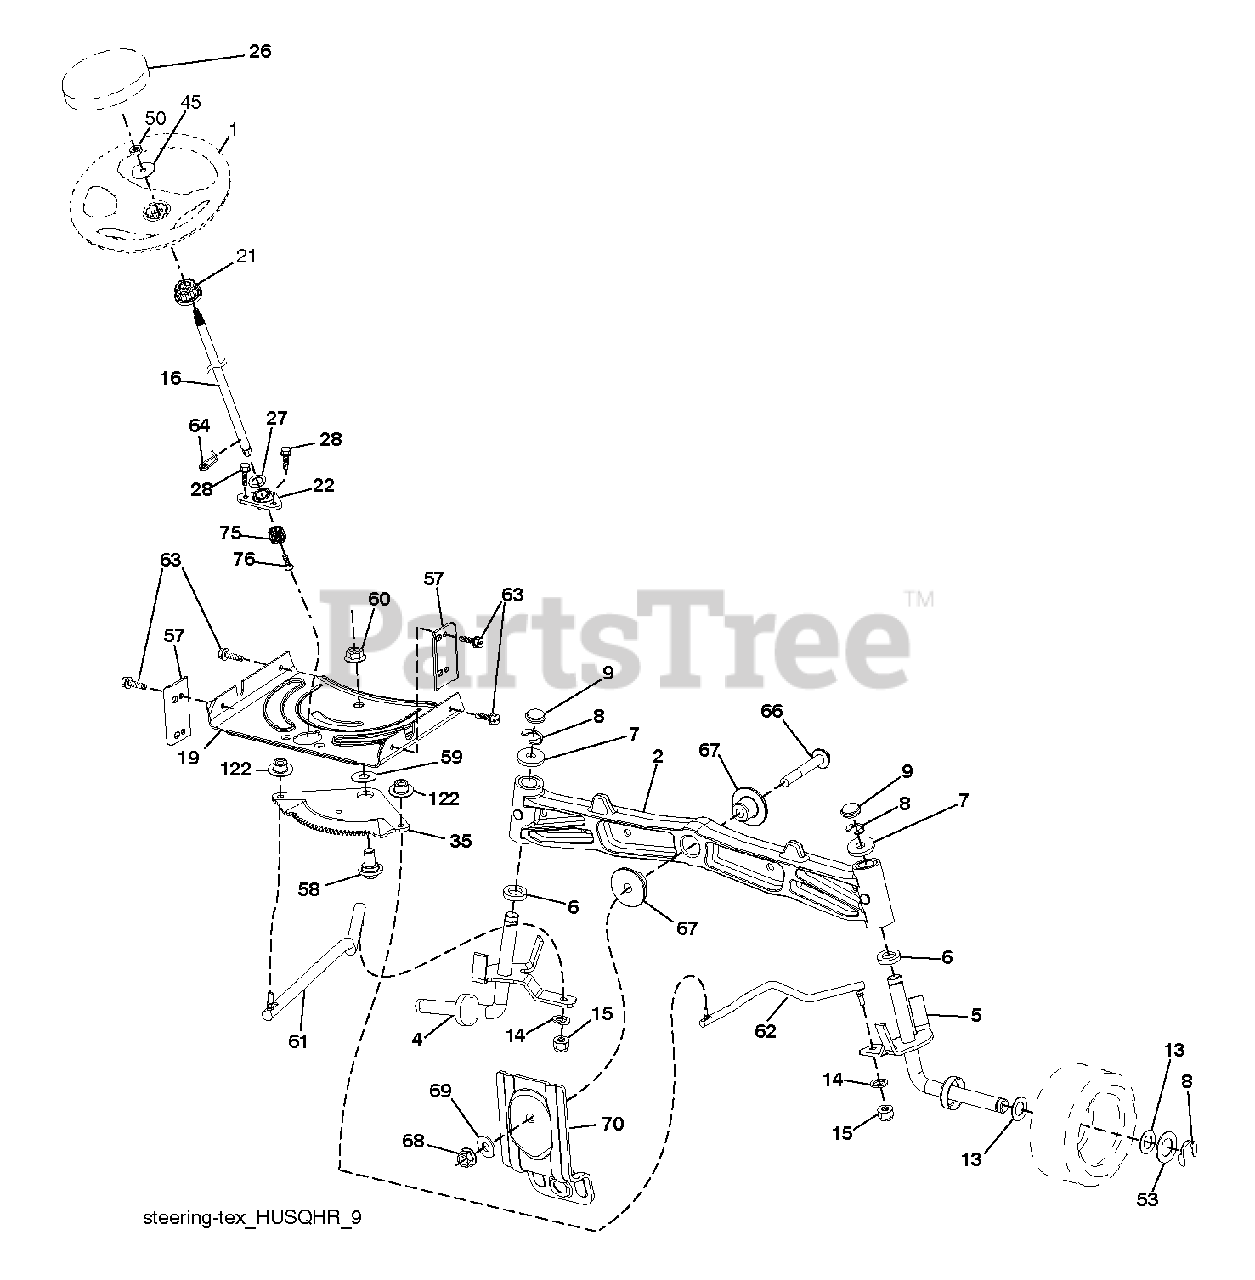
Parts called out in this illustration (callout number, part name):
1	WHEEL.STEER.HUSQ.SR.498.OVMLD
2	AXLE.CAST.IRON
4	SPINDLE.WELDED.LH.15"TEX
5	SPINDLE.WELDED.RH.15"T
6	THRUST WASHER
9	CAP.SPINDLE.BLACK
14	WASHER, LOCK 3/8
15	NUT CROWNLOCK 3/8-24
16	SHAFT.STEER.2HIGH.SPLND.PLATED
19	PLATE.STEER.DDL.NLT/NG
21	ADAPTER.WHEEL.STEER.SPLND.ALUM
22	BEARING.SHAFT.STEER.LOWER.625
26	INSERT.CAP.WHL.STRG.HUSQ.PREM
28	SCREW, 3/8-16X3/4
35	GEAR.SECTOR.PLATE.DDL.
45	WASHER.3/8ID.2-3/8OD.12GA.PLTD
50	NUT LOCK FLG 3/8-16 UNC
53	WASHER.HARDENED
57	BRACKET.UPSTOP.TEX
58	BOLT.SHOULDER.SECTOR.P
59	WASHER.THURST.SECTOR.S
60	NUT FLANGE LOCK 5/8-11
61	DRAGLINK.LH.BALLSTUD.D
62	DRAGLINK.RH.BALLSTUD.D
63	SCREW
64	RETAINER.CLIP.SPRING.S
66	BOLT HEX FGHD 7/16-14 X 3 SERR
67	BUSHING.PM.FRONT AXLE
68	NUT.LOCK.FLANGE.7/16
69	WASHER.1.5X.505X.118
70	BRACKET.FRT.DECK.SUSP.RR.MT431
75	PINION.ZINC PLATED
76	SCREW HEAD SOCKET LRVB
122	CAP.GEAR.SECTOR.TEX
